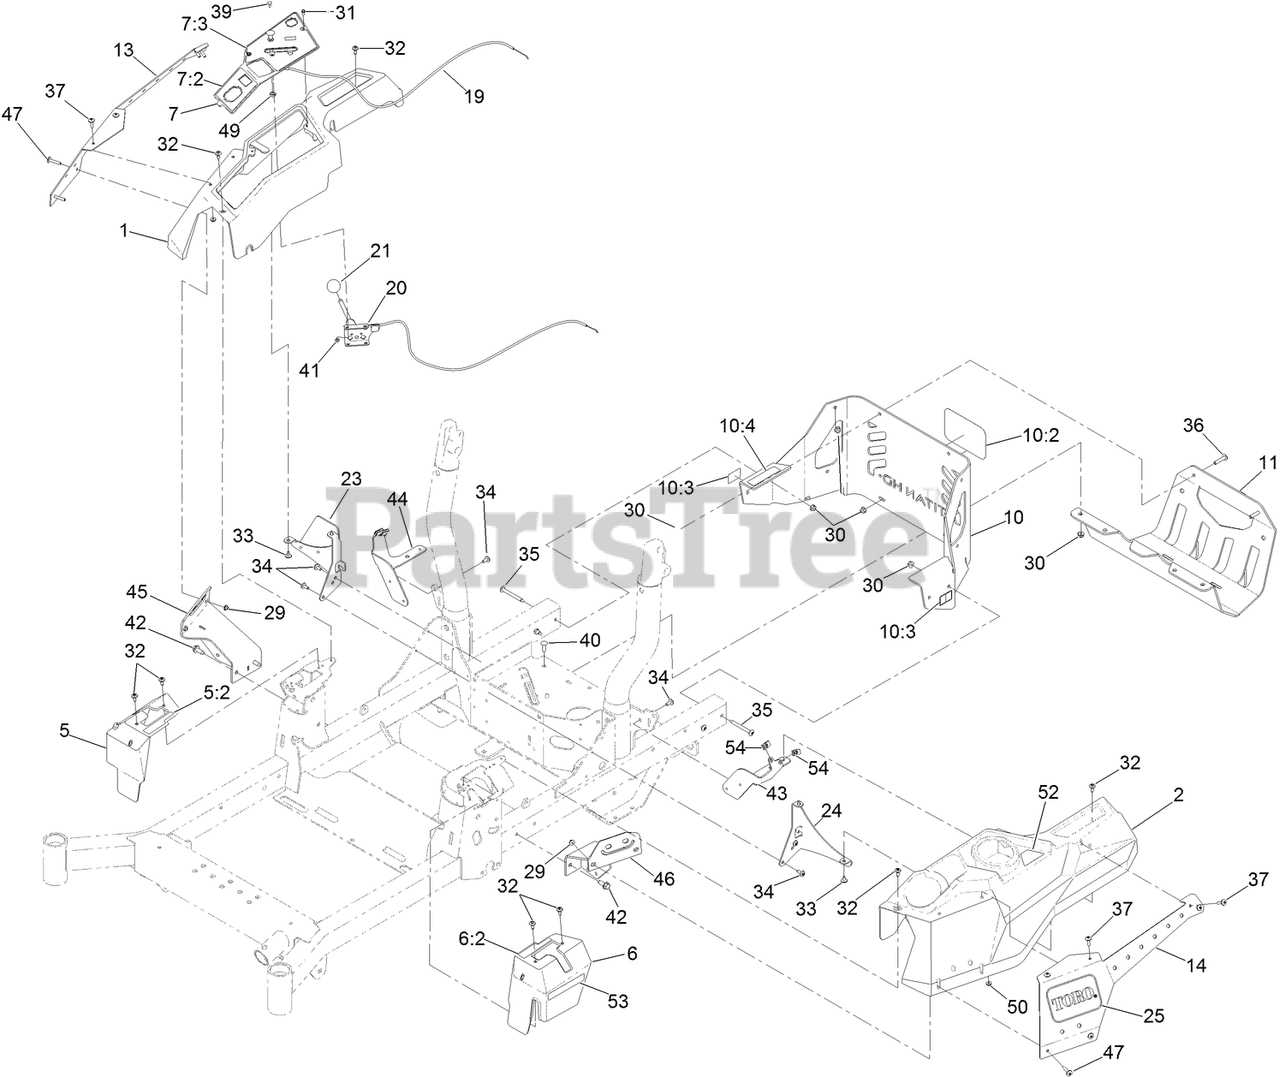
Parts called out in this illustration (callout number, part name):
1	CONSOLE-RH
2	CONSOLE-LH
5	COVER-CONTROL, MOTION (RH)
5:2	DECAL-CONTROL, MOTION (RH)
6	COVER-CONTROL, MOTION (LH)
6:2	DECAL-CONTROL, MOTION (LH)
7	CONTROL PANEL ASM
7:2	DECAL-PANEL, CONTROL
7:3	DECAL-PANEL, CONTROL
10	REAR GUARD ASM
10:2	DECAL
10:3	DECAL-WARNING
10:4	DECAL-ARRESTOR, SPARK
11	GUARD-MUFFLER
13	COVER-POD, RH
14	COVER-LH
19	CABLE-CONTROL, CHOKE
20	CABLE-CONTROL, THROTTLE
21	KNOB-BALL
23	SUPPORT-CONSOLE, RH
24	BRACKET-CONSOLE, LH
25	DECAL
29	NUT-HF
30	NUT-HF, NI
31	SCREW-HWH
32	SCREW-SHOULDER
33	SCREW-TORX
34	SCREW-TORX
35	SCREW-TORX
36	SCREW-TORX
37	SCREW-TRUSS
39	BOLT-CARR
40	SCREW-CARR
41	NUT-LOCK, NI
42	SCREW-FORMING, THREAD
43	BRACKET-SUPPORT, LEFT POD
44	BRACKET-SUPPORT, RIGHT POD
45	BRACKET-SUPPORT, POD (RH)
46	BRACKET-SUPPORT, POD (LH)
47	SCREW-TRUSS
49	NUT-HJ
50	NUT-KEPS
52	DECAL-FILL, FUEL
54	NUT-RETAINER
